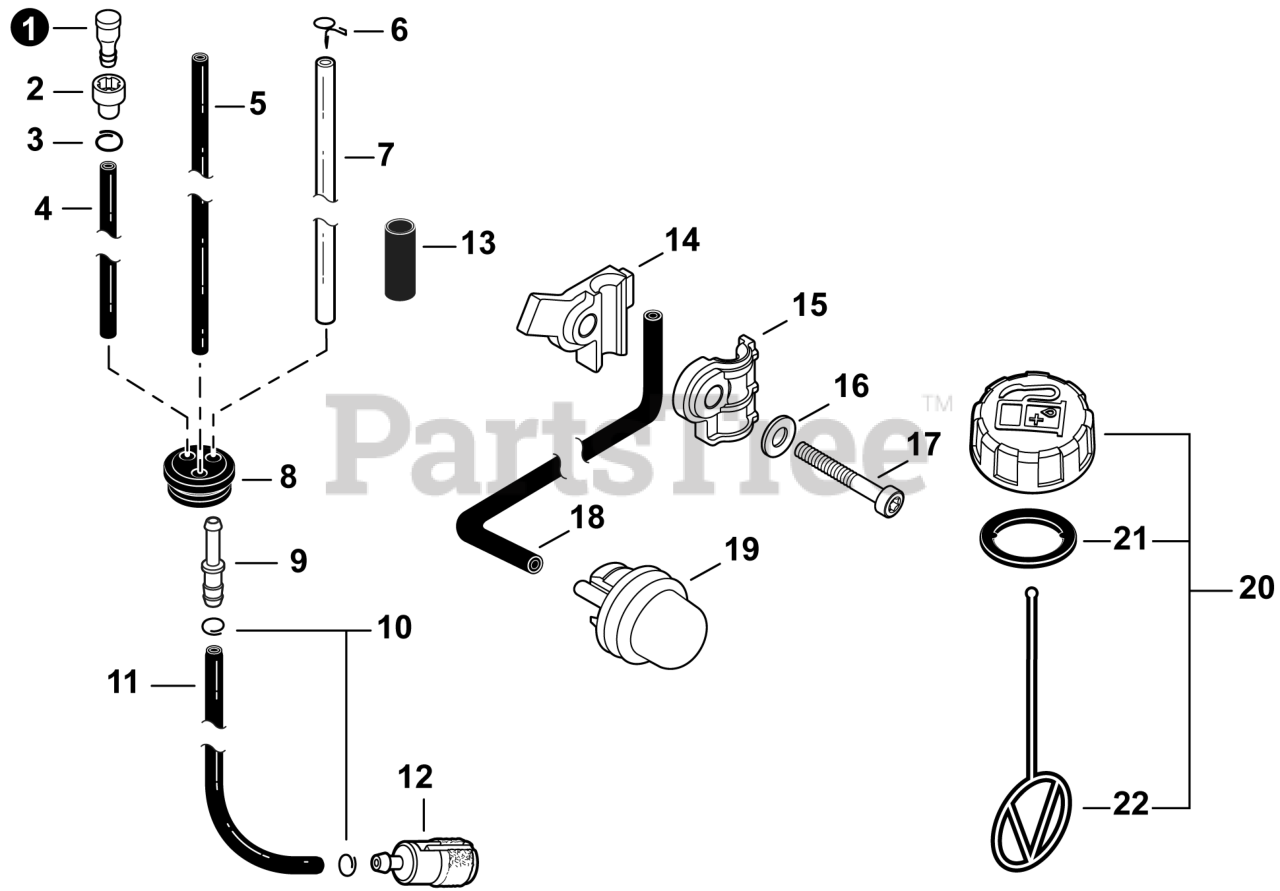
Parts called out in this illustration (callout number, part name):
1	VENT ASSY
2	HOLDER, VENT
3	CLIP Ø6.5 MM
4	PIPE, FUEL 3×6×130 BLACK
5	PIPE, FUEL 2.4×5×200 BLACK
6	CLIP, SPRING Ø5.2
7	PIPE, FUEL, 3.5X6X210 2020
8	GROMMET, FUEL
9	CONNECTOR, PIPE Ø5ר3.5
10	CLIP Ø6
11	PIPE, FUEL 3×5×105L BLACK
12	FILTER, FUEL
13	TUBE, FUEL LINE 16×18×L40
14	CLAMP, LOWER
15	CLAMP, UPPER
16	WASHER, FLAT 5.5×10×0.8
17	BOLT, TORX 5×25
18	PIPE, PURGE 2.5×5×140
19	BULB, PURGE
20	CAP ASSY, FUEL
21	GASKET, FUEL CAP
22	CONNECTOR, CAP L= 100 MM
